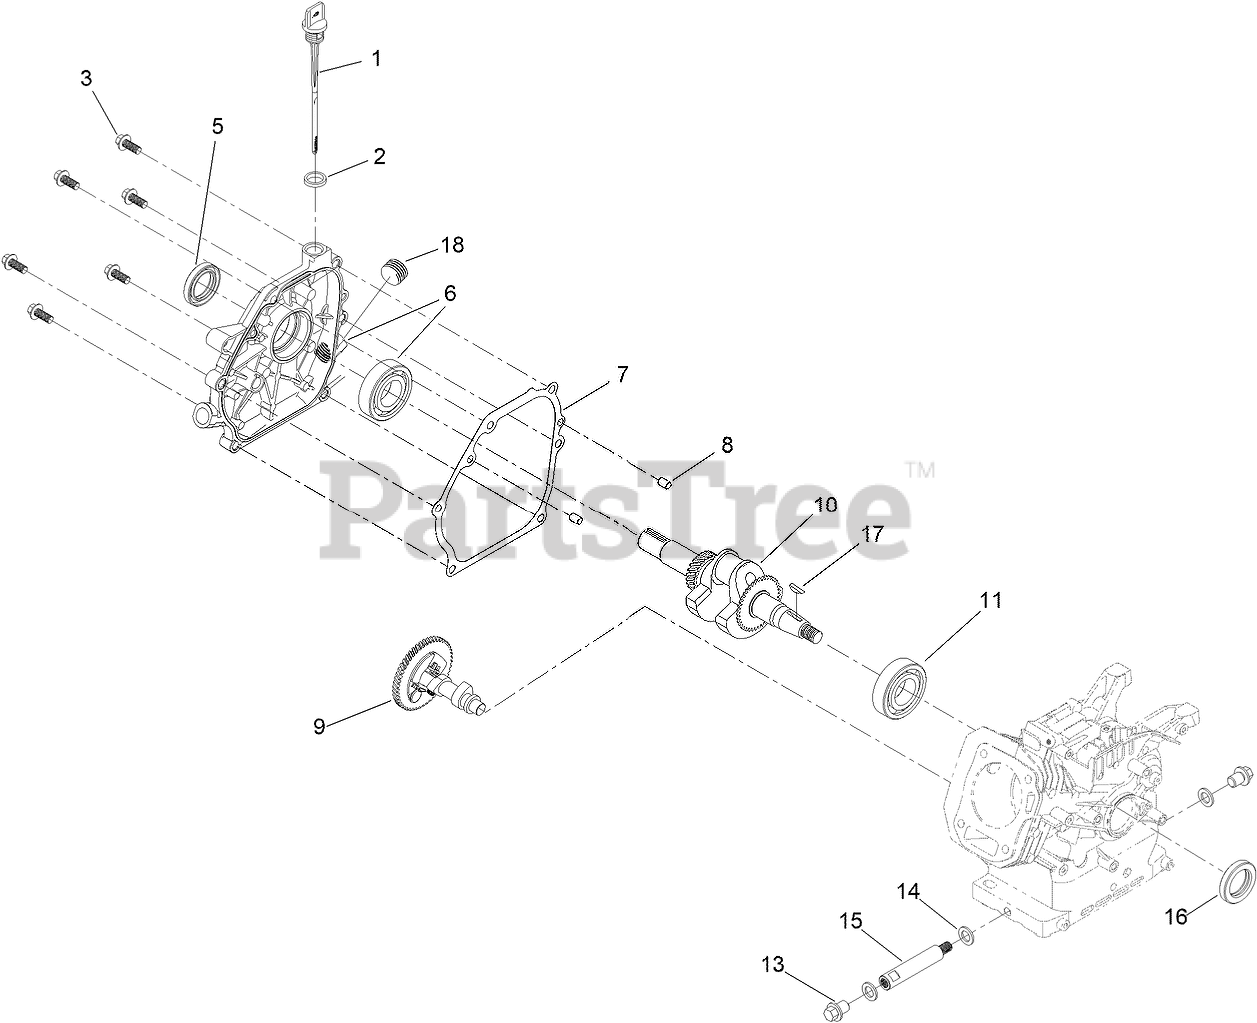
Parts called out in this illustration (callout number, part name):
1	DIPSTICK-OIL
2	GASKET-DIPSTICK, RUBBER
3	SCREW-HHF
5	SEAL-OIL
6	CRANKCASE COVER ASM
7	GASKET-COVER, CRANKCASE
8	PIN-DOWEL
9	CAMSHAFT
10	CRANKSHAFT
11	BEARING-BALL
13	SCREW-HHF
14	WASHER-PLAIN
15	TUBE-DRAIN, OIL
16	SEAL-OIL
17	KEY-WOODRUFF
18	PLUG-DRAIN
